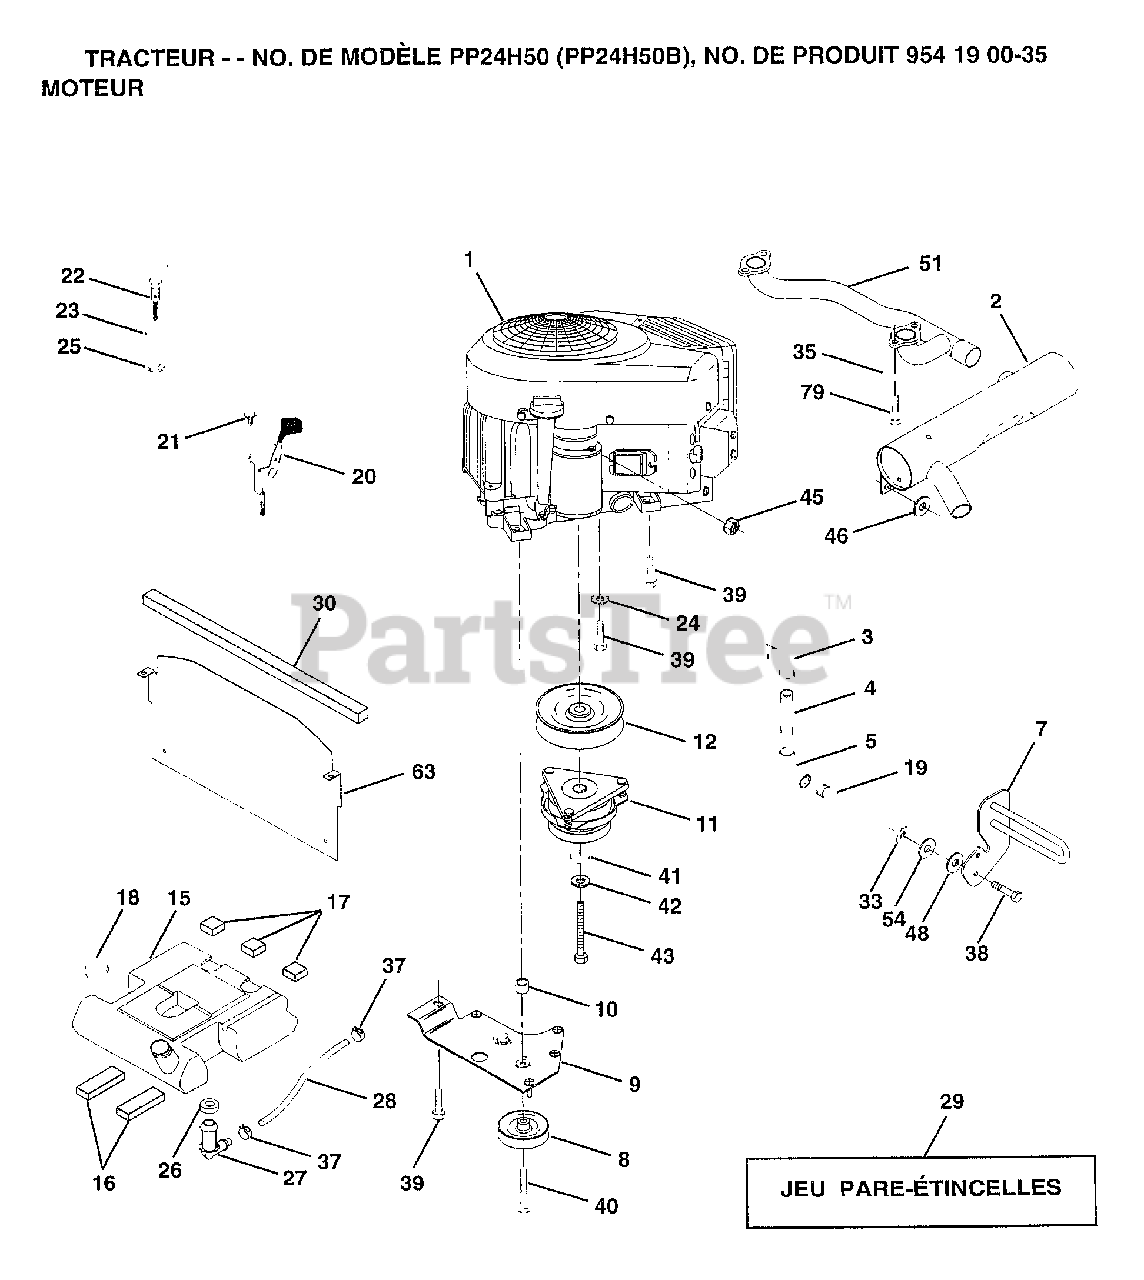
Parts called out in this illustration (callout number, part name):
2	MUFFLER.SIDE.VGT
5	ELBOW
7	GUARD.MUFFLER.ASM
9	KEEPER ASM BELT
10	BUSHING.
12	PULLEY.ENG.CLUTCH
15	TANK FUEL REAR
16	PAD IDLER TI
17	PAD-SPACER LT
18	CAP ASM FUEL
19	PLUG T
21	SCREW LT
22	CHOKE CONTROL
24	LOCKWASHER
25	"NUT,KEPS 3/8-24IM"
26	BUSHING OUTLET T
27	STEM.TANK.FUEL
29	SPARK ARREST KIT
30	EXTRUSION HOOD
32	SCREW LT
33	NUT
35	LOCKWASHER
37	HOSE CLAMP
38	"BOLT,HEX"
39	SCREW.3/8-16X2.25
40	SCREW.TT.3/8-16X4
41	WASHER
42	LOCKWASHER
43	BOLT.7/16-20X4.25
45	NUT
47	SPACER.ENGINE
48	WASHER T
51	MANIFOLD PIPE VGT
54	WASHER
55	PIPE NIPPLE LT
63	HEAT.SHIELD.VGT.
65	WASHER
74	ELBOW STREET BASS
75	SHIELD.HEAT.INTEK.VGT
76	SCREW
79	SCREW
